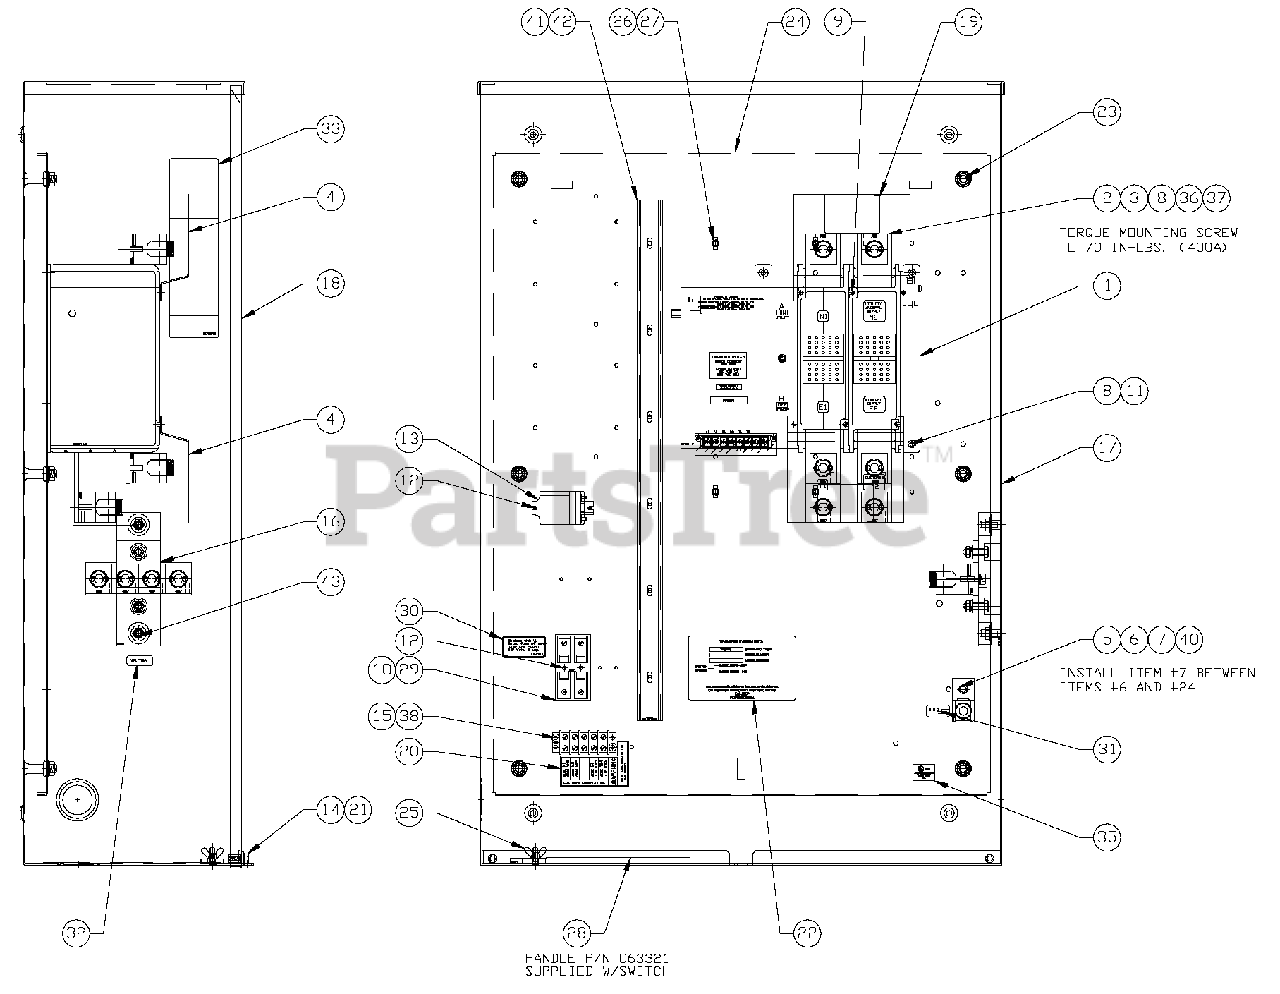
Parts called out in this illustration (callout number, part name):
1	XFER SW-W 400A600V2P
2	LUG, SLDLSS 600/250-1/0X1/4-28
3	SCREW TAPTITE #8-32X1/4 BP
4	COVER LUG 2P 400AMP
5	SCREW HHTT 5/16-18 X 3/4 CZ
6	LUG, SOLDERLESS 350-#6X13/32 AL/CU
7	WASHER SHAKEPROOF EXT 5/16 STEEL
8	WASHER LOCK M6-1/4
9	SCREW PPHM DSEMS M4-.7 X 10 ZNC
10	FUSEBLOCK 30A 600V 2POS W/SQ
11	SCREW TAPTITE M6-1.0 X 12 MM
12	SCREW TAPTITE M4-.7 X 10 MM
13	RELAY PNL 12VDC DPDT 10A@240VA
14	SCREW HHC M6-1.0 X 16 G8.8
15	RIVET, POP
16	ASSY. NEUTRAL BLOCK 300/400A
17	RTS 3R ENCLOSURE 24X36X10
18	COVER TRANSFER SWITCH
19	DECAL TERMINAL SHOCK HZD BI
20	DECAL TERMINAL STRIP
21	WASHER, NYLON
22	DECAL DATA XFER SW 100A 240V
23	NUT HEX FL WHIZ 3/8-16
24	SUBPLATE,100A TS 3R 480V
25	NUT WING M6-1.0
26	HOLDER CABLE TIE
27	TIE WRAP UL 5.6" X .10" NATL
28	HANDLE TRANSFER SWITCH 1-400A
29	FUSE 5A X BSS HLDR73591
30	DECAL,FUSE REPLACEMENT
31	DECAL GROUND LUG
32	DECAL NEUTRAL
33	DECAL MANUAL OPERATION
34	DECAL, TEST SEQUENCE
35	DECAL, UL NAMEPLATE
36	SCREW, HHCS 1/4-28 X 5/8"
37	WASHER, FLAT 1/4-6M ZINC
38	BLOCK TERM 20A 5 X 6 X 1100V
40	WASHER LOCK M8-5/16
41	DUCT WIRING 1X1.5
42	COVER WIRE DUCT 1 IN
43	NUT HEX FL WHIZ M8-1.25
